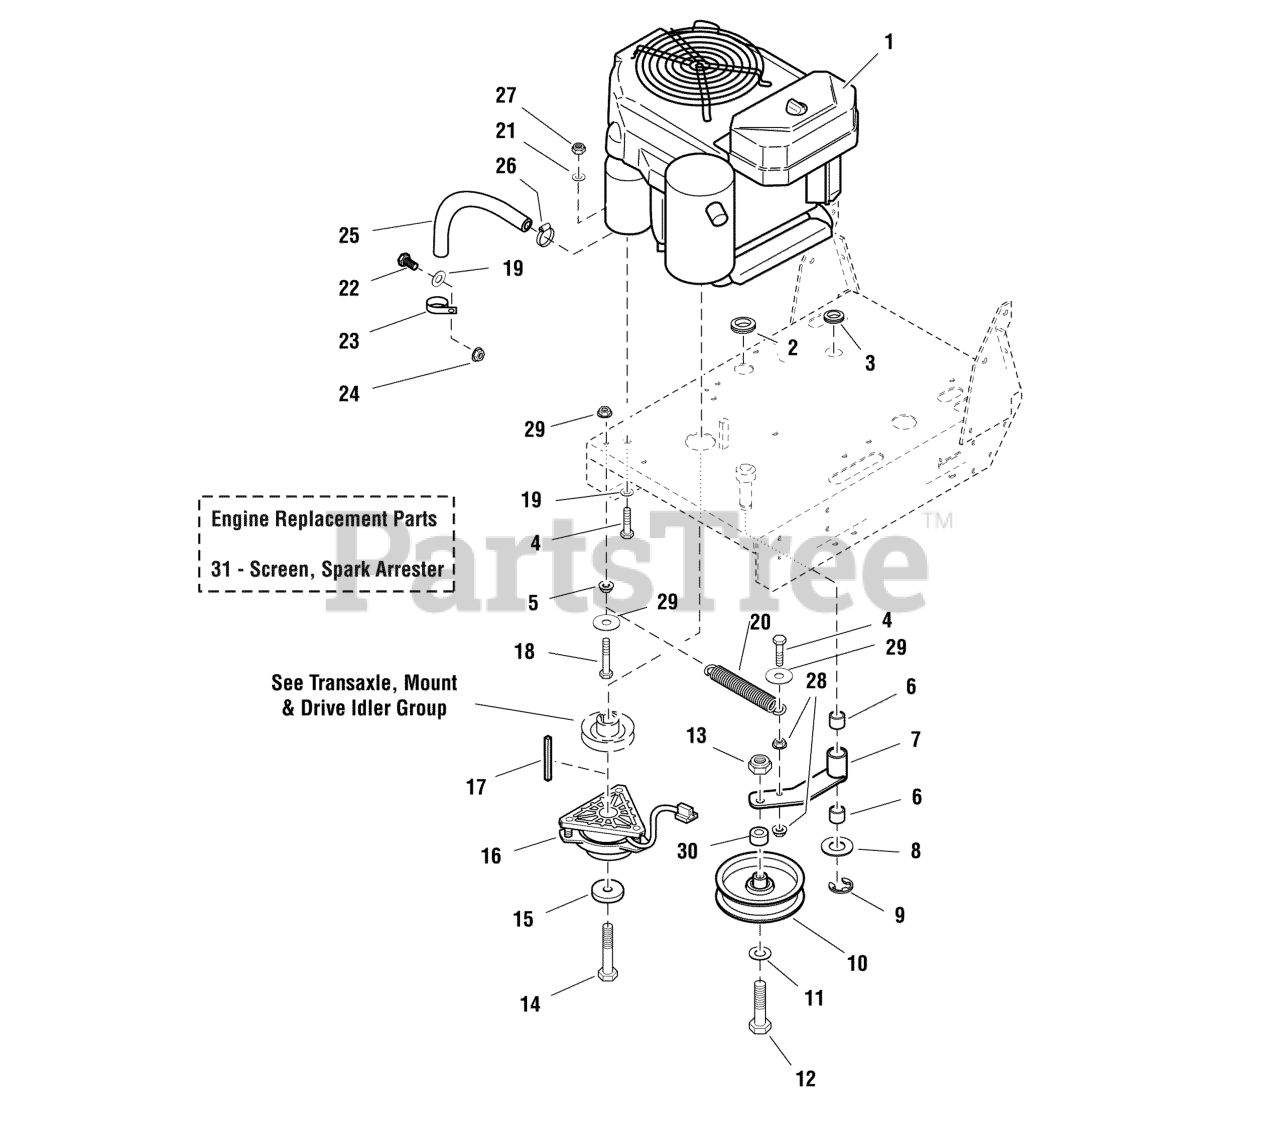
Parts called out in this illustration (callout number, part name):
1	ENGINE, 13HP KAI ELEC START
2	GROMMET, 7/8
3	GROMMET, 1/2
4	BOLT, 5/16-18 X 1-1/2" GD5 YZ
5	NUT, 5/16-18 HEX SERRATED FLANGE (LARGE)
6	BUSHING, BRASS, 3/4 X 1 X 1
7	DECK DRIVE IDLER ARM
8	WASHER, 3/4 SAE
9	C-CLIP
10	IDLER PULLEY
11	WASHER, 1/2 SAE
12	BOLT, 1/2-13 X 2-1/2" GD5 CZ
13	NUT, 1/2-13 HEX NYLON LOCK
14	BOLT, CRANKSHAFT, 7/16"X2.75
15	SPACER, .45 x 1.62 x .37
16	CLUTCH, OGURA, 74 ft lbs - 1"
17	KEY, 1/4 SQ. X 2
18	BOLT, 5/16-18 X 2-1/4 TFL, GD5 YZ
19	WASHER, 5/16" SAE
20	SPRING, Extension
21	WASHER, 5/16" SAE
22	BOLT, 5/16-18 X 3/4 GD5
23	CLAMP, HOSE, 1.000 DIA.
24	NUT, 5/16-18 HEX SERRATED FLANGE (SMALL)
25	HOSE, 1/2" PUSH-ON, 10.50"
26	CLAMP, #6 HOSE, STAINLESS
27	NUT, 5/16-18 HEX NYLON LOCK
28	NUT, 5/16-18 Hex Nylon Flange
29	WASHER, 5/16" USS
30	SPACER, .52 x 1.00 x .38
31	SCREEN, SPARK ARRESTER-KAWI 13, 17, 19HP
